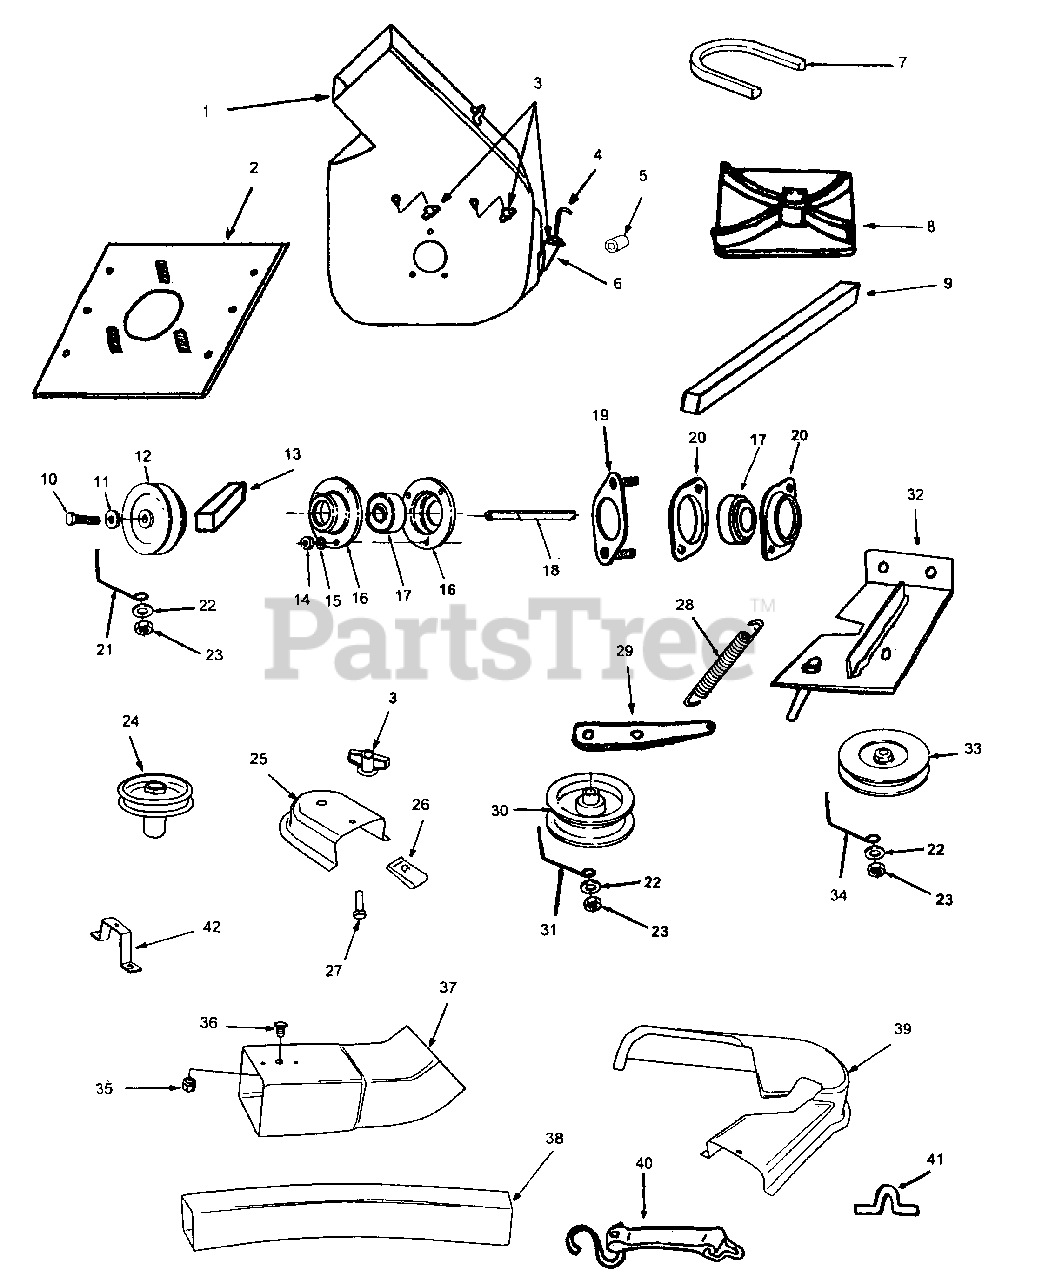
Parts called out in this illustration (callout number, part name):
1	Blower Hsg. w/Liner
2	Brg. Supt. Plate Assy.
3	Wing Nuts
4	Frt. Supt. Mounting Rod
5	Spacer, .320 X .625 X .92
6	Deck Stop Brkt.
7	Belt
8	Blade Implr.
9	Implr. Shaft Key
10	Hex Bolt 5/16-18 X 3/4 Lg.
11	Wsh .345 I.d. X 1.385 o.d. X .120 Thk.
12	Implr. Pulley
13	Implr. Pulley Key
15	(Not Used In Application) (Purchase Locally)
16	Outer Brg. Supt. Flange
17	Implr. Shaft Brg.
18	Implr. Shaft
19	Supt. Brg. Flange
20	Inner Supt. Brg. Flange
21	Implr. Pulley Belt Guide
22	Wsh. .305 I.d. X .740 o.d. X .062 Thk.
24	Driven Threaded Pulley
25	Small Belt Guard
26	U-Type Clip Nut 1/4-20
27	Hex Cap Screw 1/4-20 X 7/8
28	Idler Tension Spring
30	Flat Idler Pulley
31	Flat Idler Pulley Belt Guide
32	Idler Plate Assy.
33	V Idler Pulley
34	V Idler Pulley Belt Guide
37	Short Chute
39	Large Belt Guard
42	Blower Hsg. Retaining Brkt.
